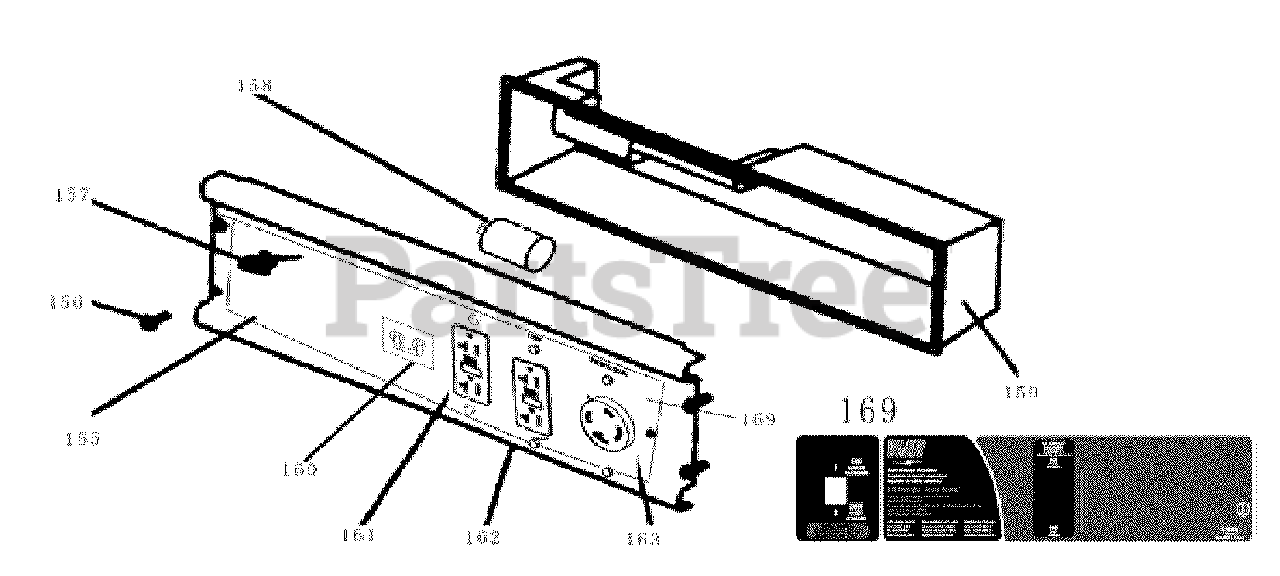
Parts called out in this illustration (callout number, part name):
155	Control panlle
156	boltM6x 12
157	Engine switch
158	capacitor
159	Control panle cover
160	circuit breaker
161	120V GFCI receptacle
162	120V GFCI receptacle
163	120/240 receptacle
169	control panle label
